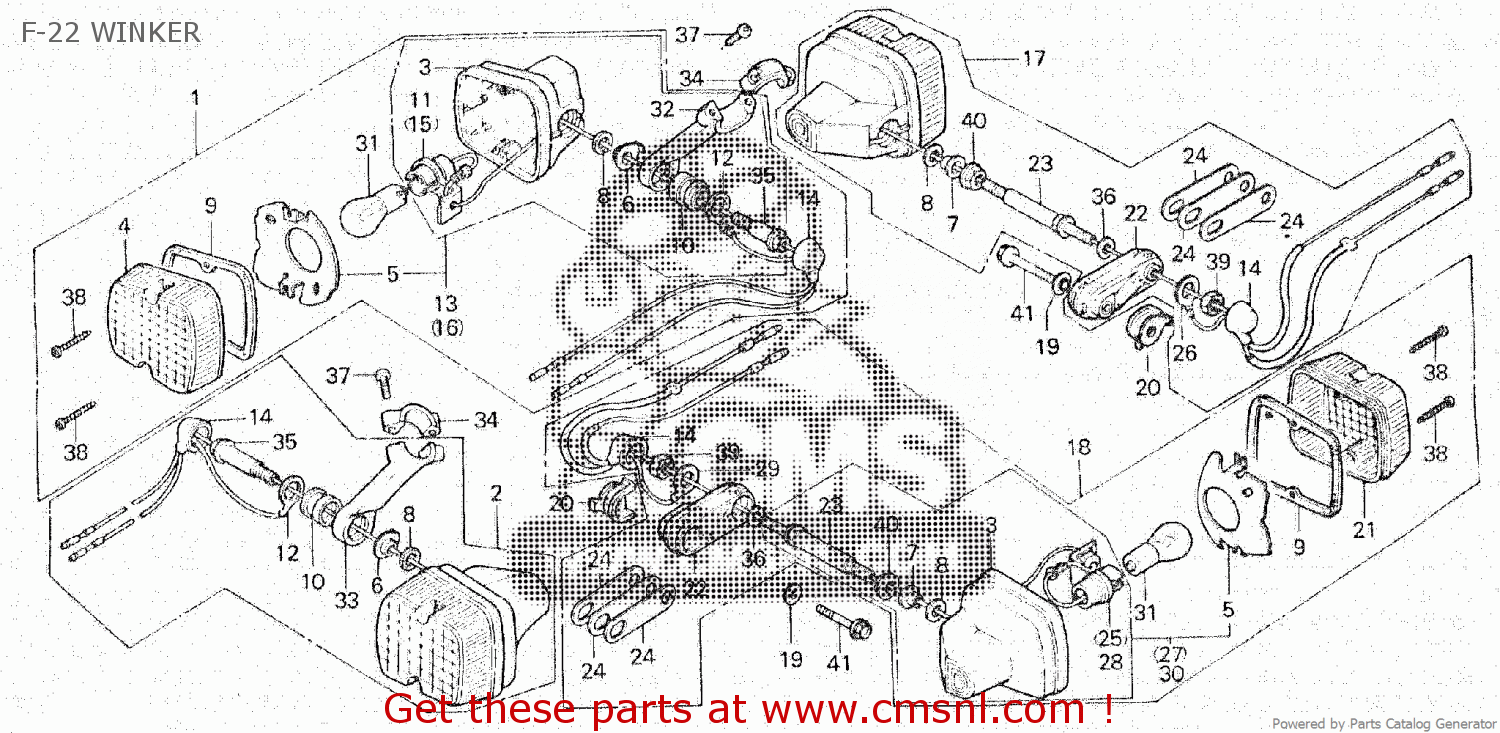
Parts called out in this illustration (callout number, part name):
1	WINKER SET,R.FR.
2	WINKER SET,L.FR.
3	BASE,WINKER
4	LENS,WINKER
5	REFLECTOR
6	STOPPER,FR.WINKER
7	COLLAR,WINKERBASE
8	SEAL,GASKET
9	LENS,GASKET
10	RUB,FR.WINKER MT.
11	SOCKET R WINKER
12	CORD,WINKER EARTH
13	BASE,R.FR.WINKER
14	COVER,WINKER CORD
15	SOCKET L WINKER
16	BASE,L.FR.WINKER
17	WINKER SET,R.RR.
18	WINKER SET,L.RR.
19	WASHER,RR.WINKER
20	STAY,RR.WINKER
21	LENS,WINKER
22	RUB RR WINKER
23	BOLT,RR.WINKER
24	SPRING,RR.WINKER
25	SOCKET R RR
26	CORD WINKER EARTH
27	BASE,R.RR.WINKER
28	SOCKET L RR
29	CORD WINKER EARTH
30	BASE,L.RR.WINKER
31	BULB,WINKER
32	BRKT R FR WINKER
33	BRKT L FR WINKER
34	HOLD,WINKER STAY
35	BOLT,WINKER SET
36	WASHER (10.2X20)
37	SCREW,CROSS,5X16
38	SCREW,TAPPING4X25
39	NUT,HEX.,10MM
41	BOLT, FLANGE,6X60
